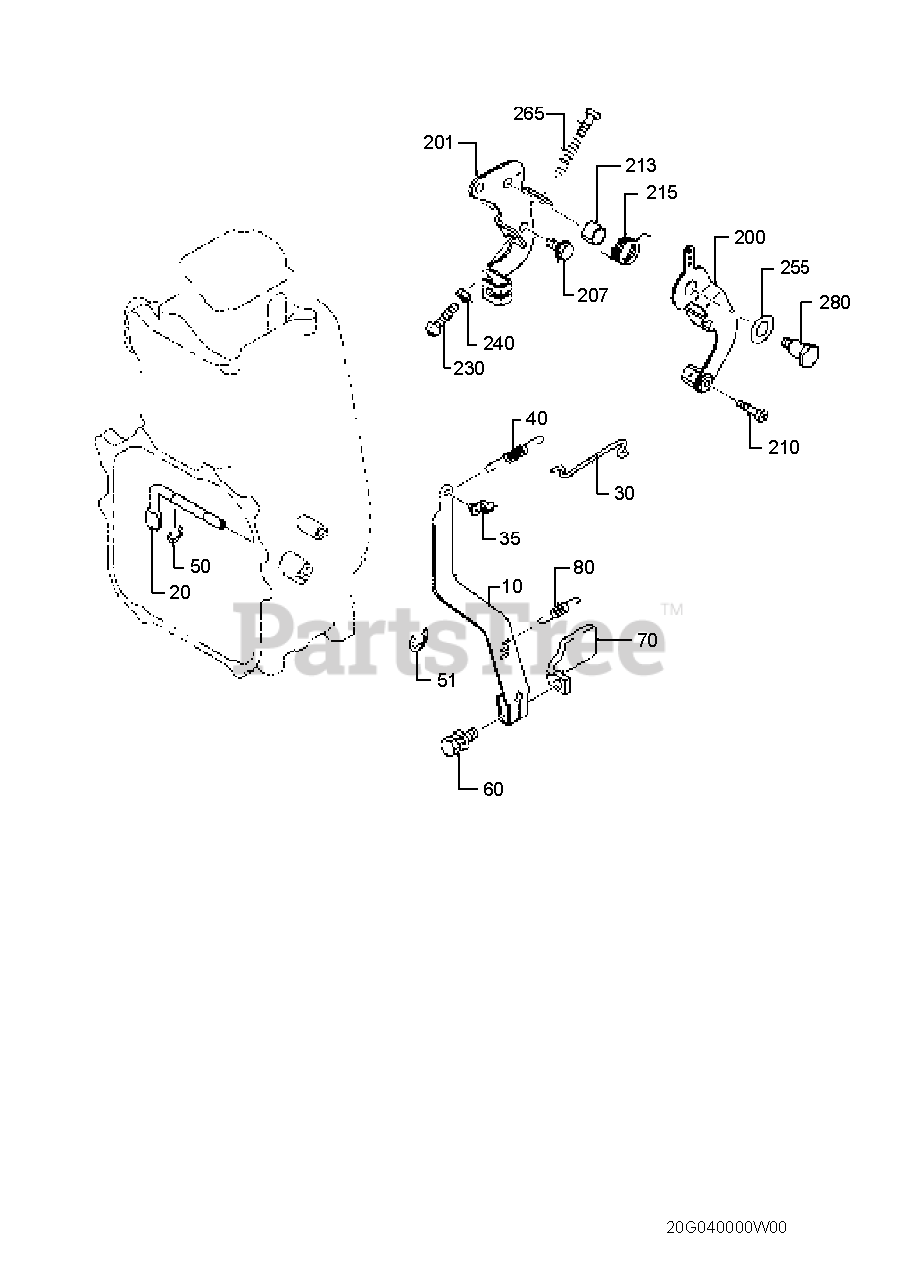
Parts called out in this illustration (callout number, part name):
10	GOVERNOR LEVER
20	GOVERNOR SHAFT
35	LINKAGE BUSHING
60	BOLT AND WASHER AY
70	WEIGHT CP
80	GOVERNOR SPRING
200	SPEED CONTROL AY
210	SCREW, PANHEAD
255	FRICTION WASHER
265	CONTROL SPRING
